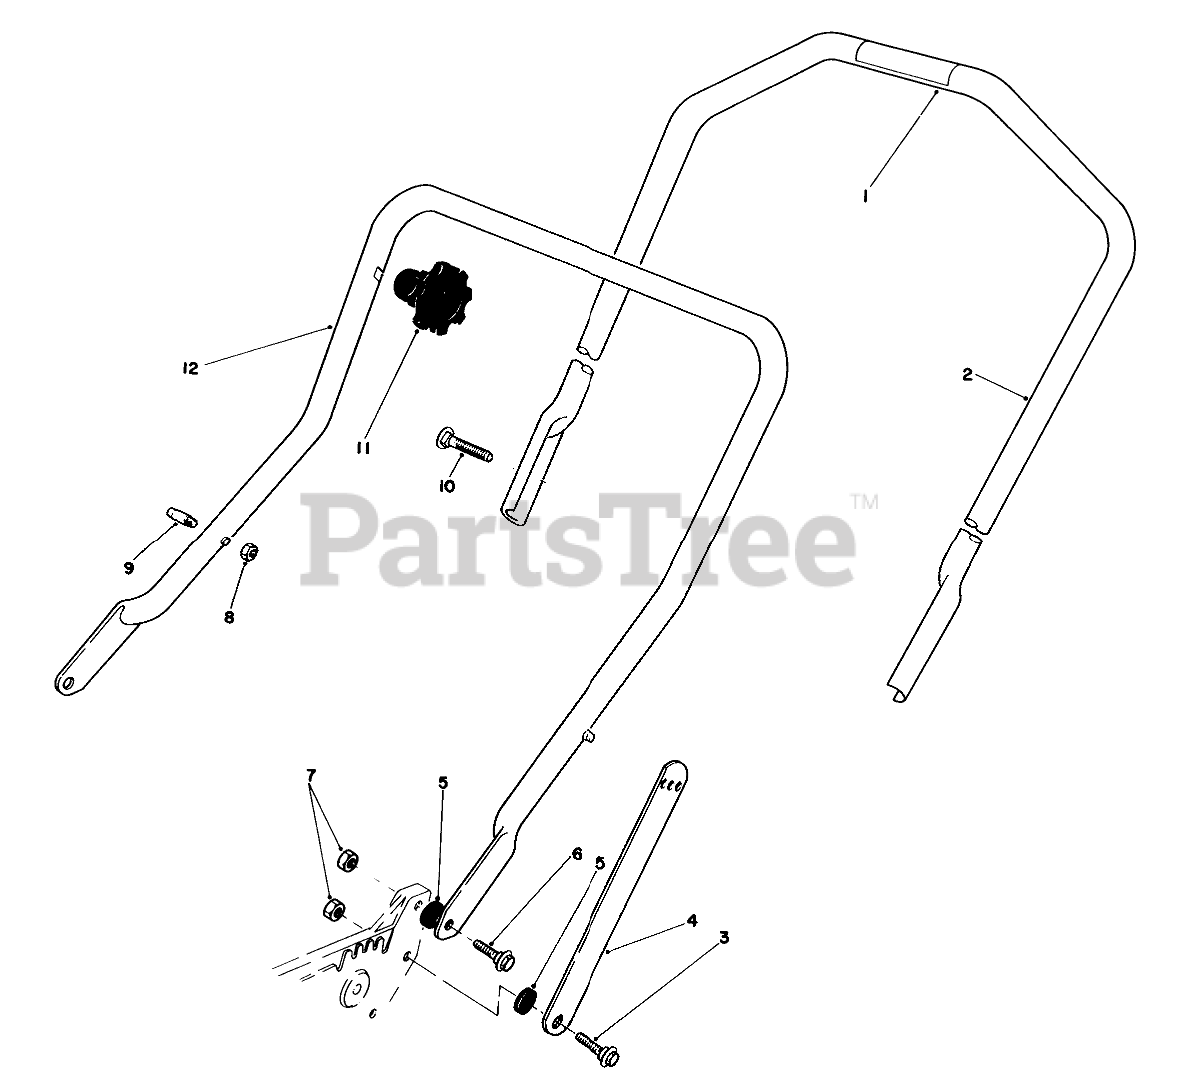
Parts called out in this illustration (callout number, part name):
1	DANGER DECAL
2	Handle-Upper (Incl. Ref. #1)
3	SCREW-SHOULDER
4	Handle Latch
5	SPACER
6	SCREW-SHOULDER
7	NUT-LOCK, NI
8	NUT-LOCK, NI
9	HANDLE PIN
10	5/16-18 X 2 HNDLE SCREW
12	Handle-Lower
